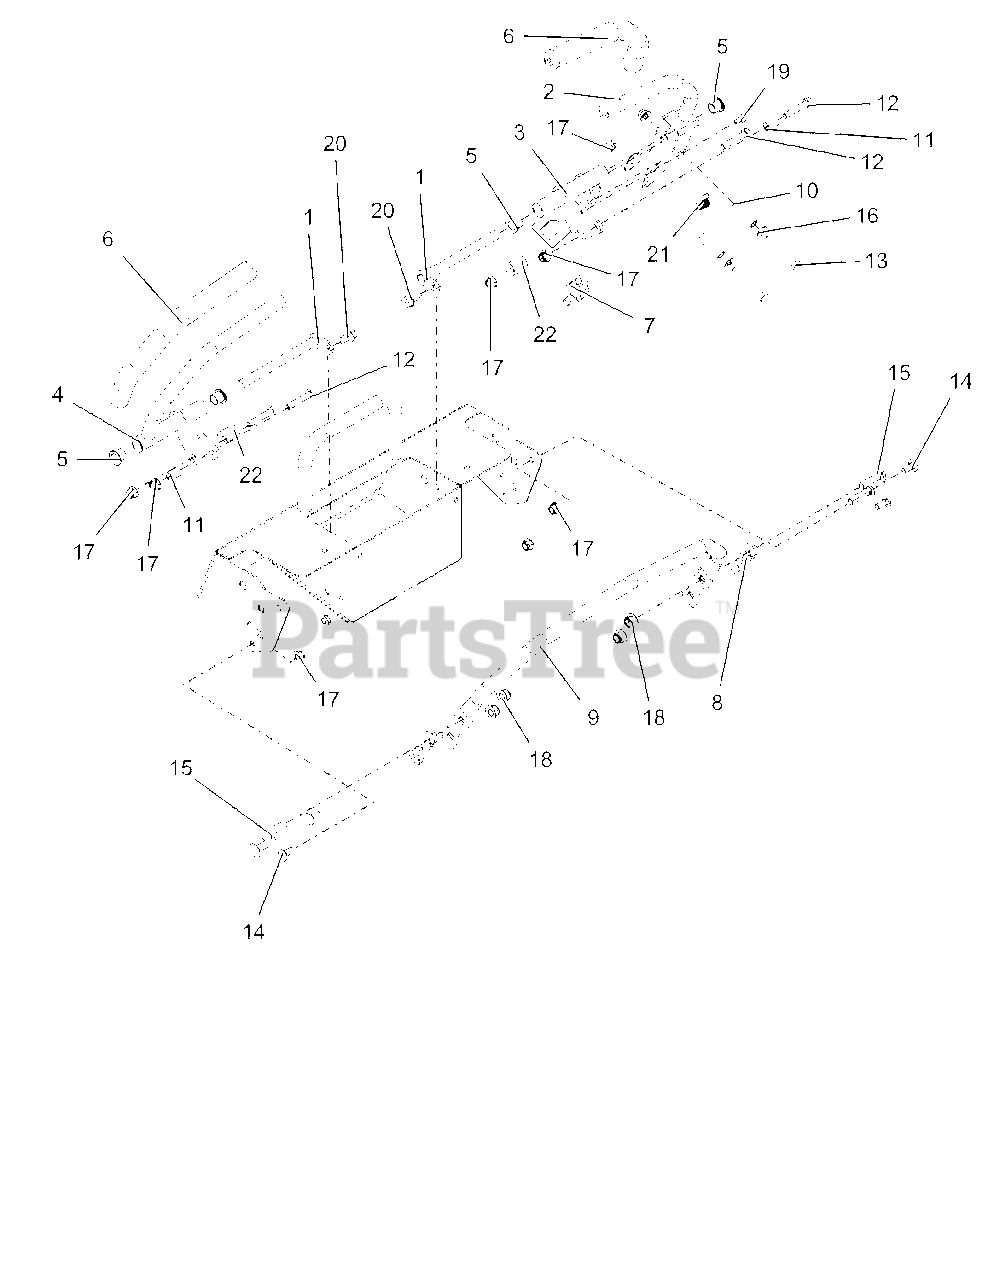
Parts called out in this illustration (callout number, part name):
1	WLDT, PIN AND LOCK Y
2	WMT, CONTROL ARM OPC
3	WMT, CONTROL ARM (LH)
4	WMT, CONTROL ARM (RH)
5	BRG, FLG .500X.620X.500 BRNZ
6	GRIP, HANDLEBAR
7	SWITCH- SNAP MTG N.O.
8	SHIM, 5 DEG SPEED BAR
9	BAR, FORWARD STOP PRO-STANCE
10	BSHG-SLV .325X.49X1.56
11	BSHG-SLV .328X.50X.75
12	@BLT-HEX .31-18X1.75 GR5 YWZC
13	@BLT-HEX .31-18X2.25 GR5 YWZC
14	@BLT-RDHDSQNK .31-18X.75 G5YZ
15	@BLT-RDHDSQNK .38-16X1.50 G5YZ
16	@WSHR-FL-STL.344X.688X.065YWZC
17	@NUT-LK-NYL-FLG .31-18 YWZC
18	@NUT-LK-NYL-FLG .38-16 YWZC
19	SCR-TAP .25-20X.50 HWH TR YWZ
20	@SCR-TAP .38-16X.75 HWH TR YWZ
21	SPRING, EXT. .043X.438X1.64
22	ECCENTRIC
